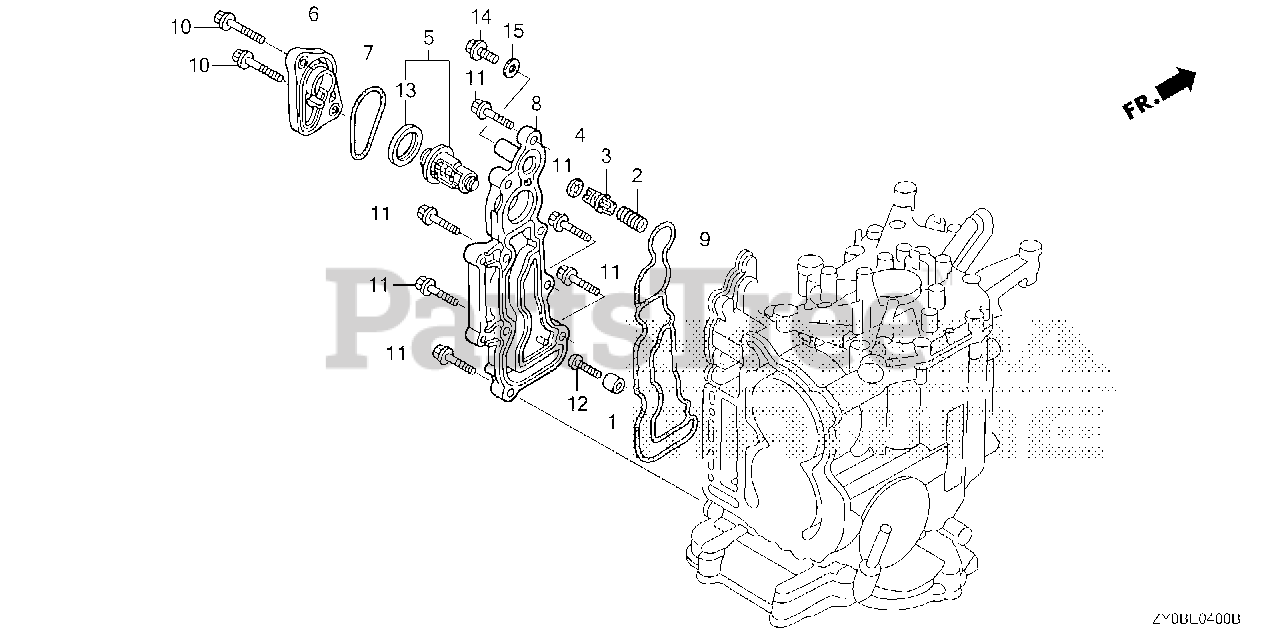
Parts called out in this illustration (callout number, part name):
1	METAL, ANODE
2	SPRING, FLUSH VALVE
3	VALVE, FLUSH
4	GASKET, FLUSH VALVE
5	THERMOSTAT ASSY.
6	COVER, THERMOSTAT
7	O-RING, THERMOSTAT COVER
8	COVER, WATER JACKET
9	GASKET, EX. WATER JACKET COVER
10	BOLT, FLANGE (6X36) (CT200)
10	BOLT (6X36) (CT200)
11	BOLT, FLANGE (6X22) (CT200)
12	BOLT, FLANGE (5X20)
12	SCREW, PAN (5X20)
13	RUBBER, RING
14	BOLT, SPECIAL (8MM)
15	GASKET (8MM)
